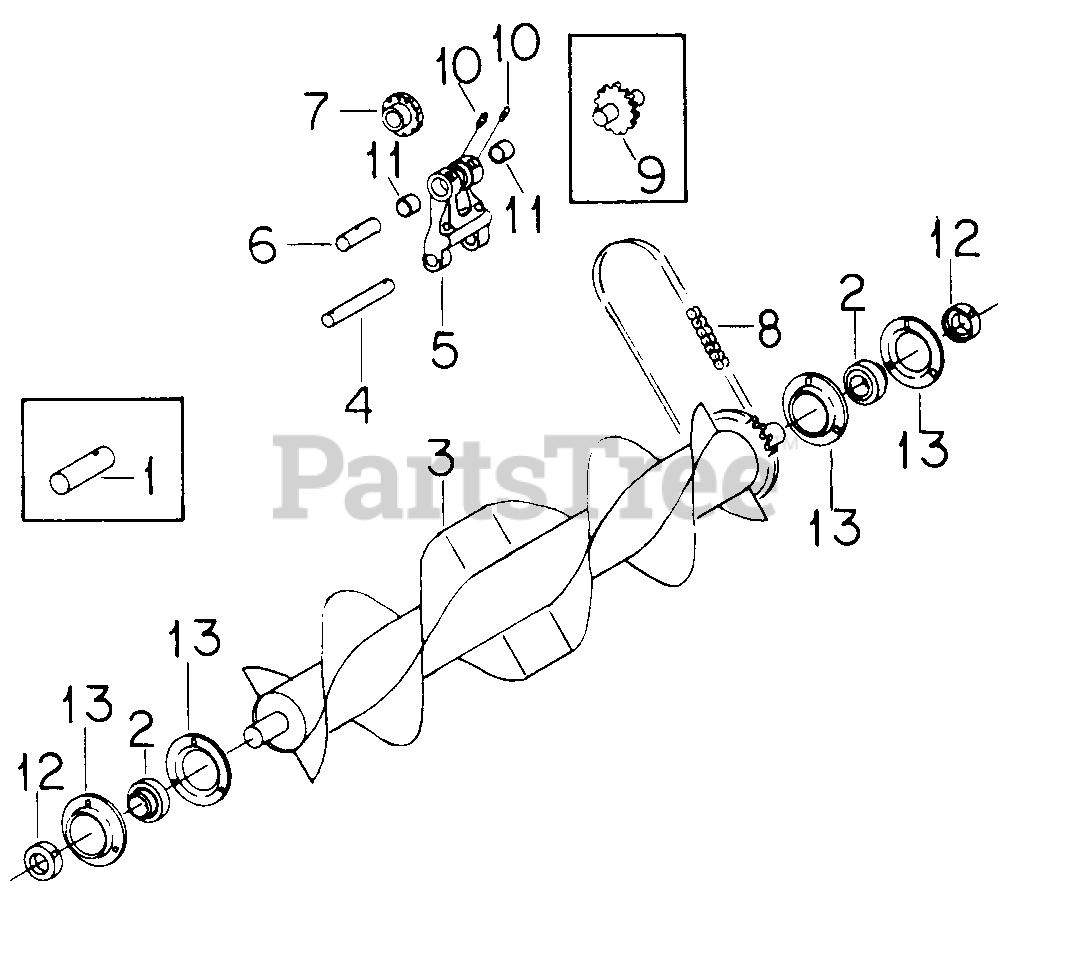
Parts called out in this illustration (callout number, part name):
1	Shaft, Tail -Used with Rotors 397 028 R1 & 397 029 R1
2	Bearing w/o Locking Collar
3	Rotor Assy -For QA 36A Snow Thrower- -Order Rotor Assy 59 746 C1
4	Pin, Mounting
5	Bracket, Sprocket Mounting
6	Shaft, Transfer
7	Sprocket, Small - 14 T
8	Chain, Roller - For 24 Tooth Sprocket
9	Sprocket Assy, Rotor -Used with Rotors 397 028 R1 & 397 029 R1
10	Fitting, 1/4-28 Ptf Str Lub
11	Bearing, Needle
12	Collar Assy, Locking
13	Flange, Bearing Mtg
